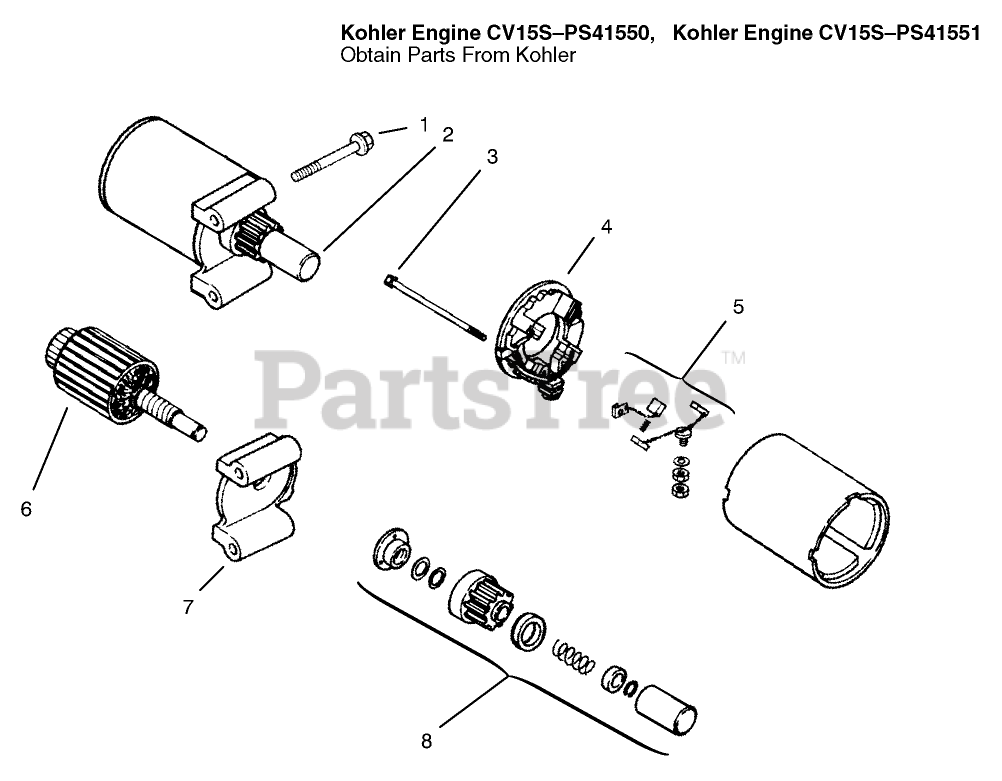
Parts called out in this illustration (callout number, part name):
1	Screw M8x1.25x70 (Only On: 72042, 72063, 72062, 72043)
2	Starter ASM Incl 3-8
3	Bolt
4	Commutator-End Cap
5	Kit-Brush
6	Armature
7	Cap-Drive End
8	Kit-Drive
